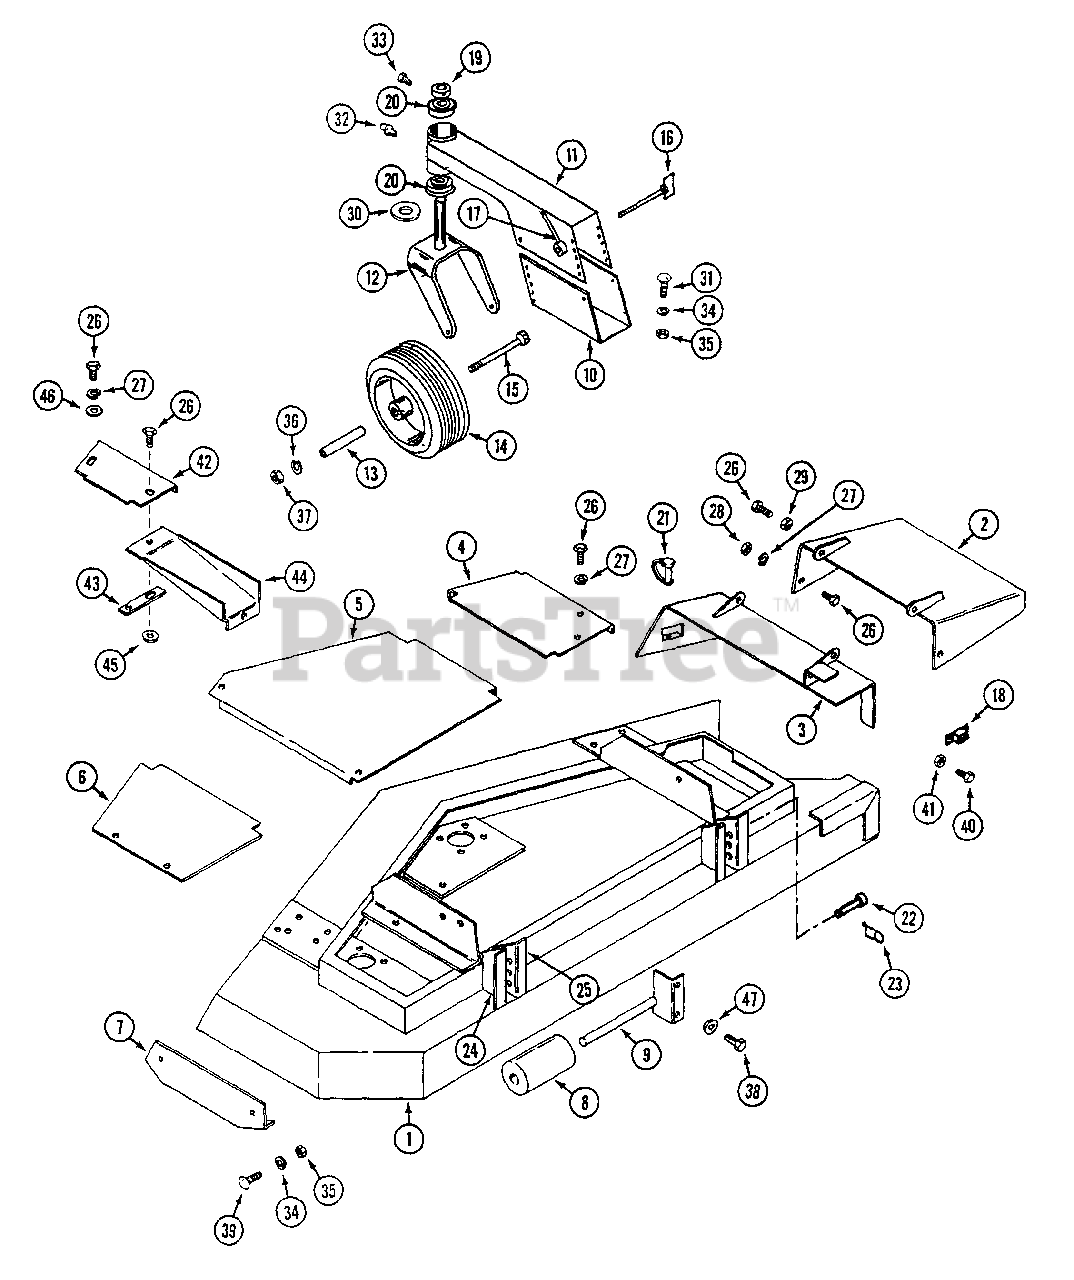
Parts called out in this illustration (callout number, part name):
2	CHUTE - foot guard
3	MOUNT - foot guard
5	COVER - center
8	ROLLER - anti-scalp
9	SHAFT - roller
10	BRACKET - gauge wheel mount
11	MOUNT - gauge wheel
14	WHEEL - gauge
15	BOLT - 1/2" - 13 x 6-1/2"
17	NUT - gauge wheel handle
18	BREAKER - circuit, 10 amp
21	PIN - "fas-tatch"
23	PIN - cotter, hair
24	BRACKET - height adjust LH.
25	BRACKET - height adjust R.H.
26	BOLT - 1/4" - 20 x 3/4"
27	LOCKWASHER - 1/4"
28	NUT - 1/4" - 20
29	NUT - 1/4" - 20 lock
30	WASHER - thrust
31	BOLT - 5/16" - 18 x 1" carriage
32	FITTING - grease
33	SCREW - set 5/16" - 18 x 1/2" square head
34	LOCKWASHER - 5/16"
35	NUT - 5/16" - 18
36	LOCKWASHER - 1/2"
37	NUT - 1/2" - 13
38	BOLT - 5/16" - 18 x 3/4"
39	BOLT - 5/16" - 18 x 3/4" carriage
40	SCREW - #10 - 32 x 1/2"
41	NUT - #10 - 32
42	COVER - center, small
43	STRAP - cover
44	COVER - center, rear
45	NUT - 1/4" - 20 flange lock
46	WASHER - 1/4"
47	NUT - 5/16" - 18 flange lock
